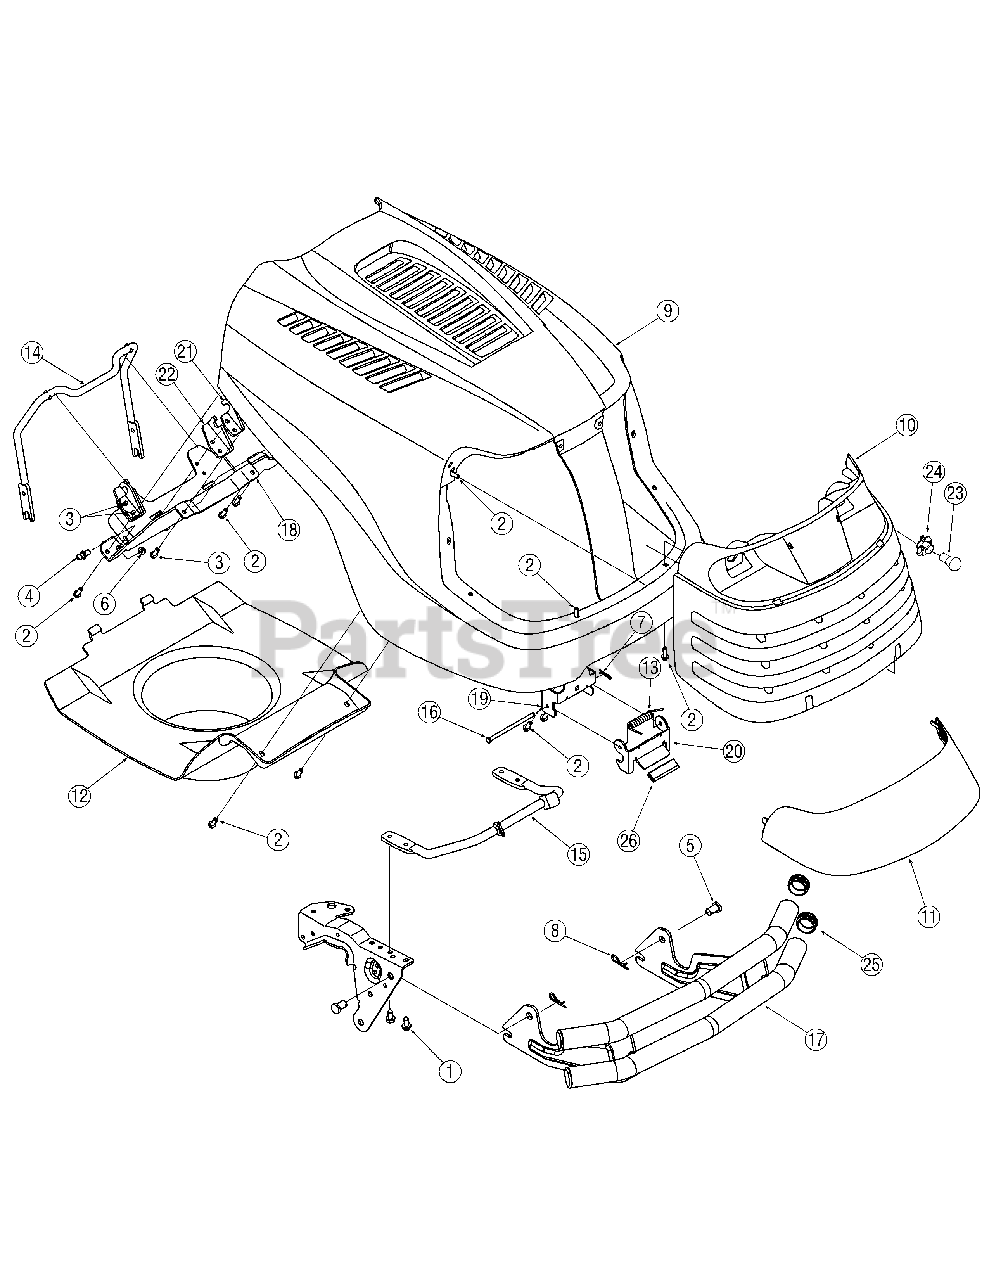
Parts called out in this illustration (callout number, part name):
1	Screw, 5/16-12 x.750
2	Screw, 1/4-15 x.750
3	Screw, Self Tapp, 1/4-20 x.750
4	Screw, Ball, 5/16-18 x.56
5	Pin, Clevis,.50 Dia. x.78
6	Nut, Flange Lock, 5/16-18
7	Pin, Cotter,.072 Dia. x 1.13
8	Pin, Click,.092 x 1.64
9	Hood, Service Kit
9	Hood
9	Push Nut .25ID x .50 OD
9	Screw, Hi Low 5/16-14 x .75
10	Grill
11	Lens
12	Hood Plenum
13	Latch Spring
14	Hood Pivot Rod
15	Hood Latch Rod
16	Rod,.250 Dia. x 4.55
20	Latch Pivot Bracket
21	Upper Pivot Bracket
22	Hood Pivot Bracket
23	Miniature Lamp, 12V
24	Lamp Socket
25	Cap, Bumper
26	Vinyl Strip, 2.5"
